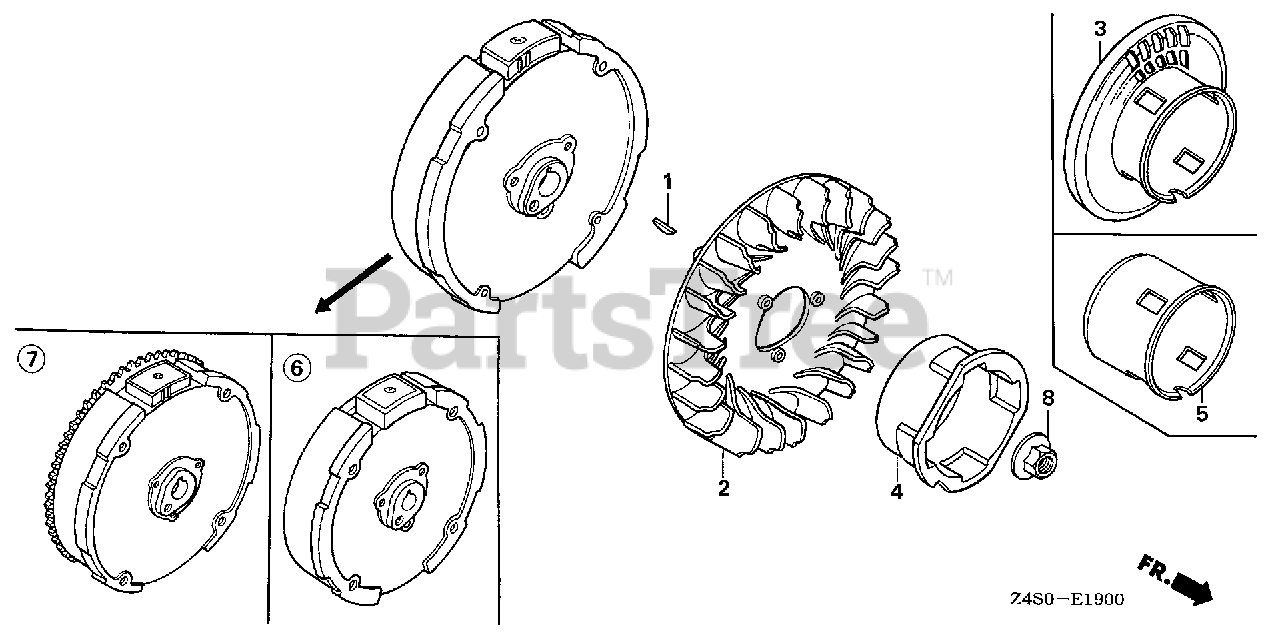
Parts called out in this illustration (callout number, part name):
1	KEY, SPECIAL WOODRUFF (25X18)
2	FAN, COOLING
3	PULLEY, STARTER
6	FLYWHEEL (STD)
8	NUT, SPECIAL (14MM)
